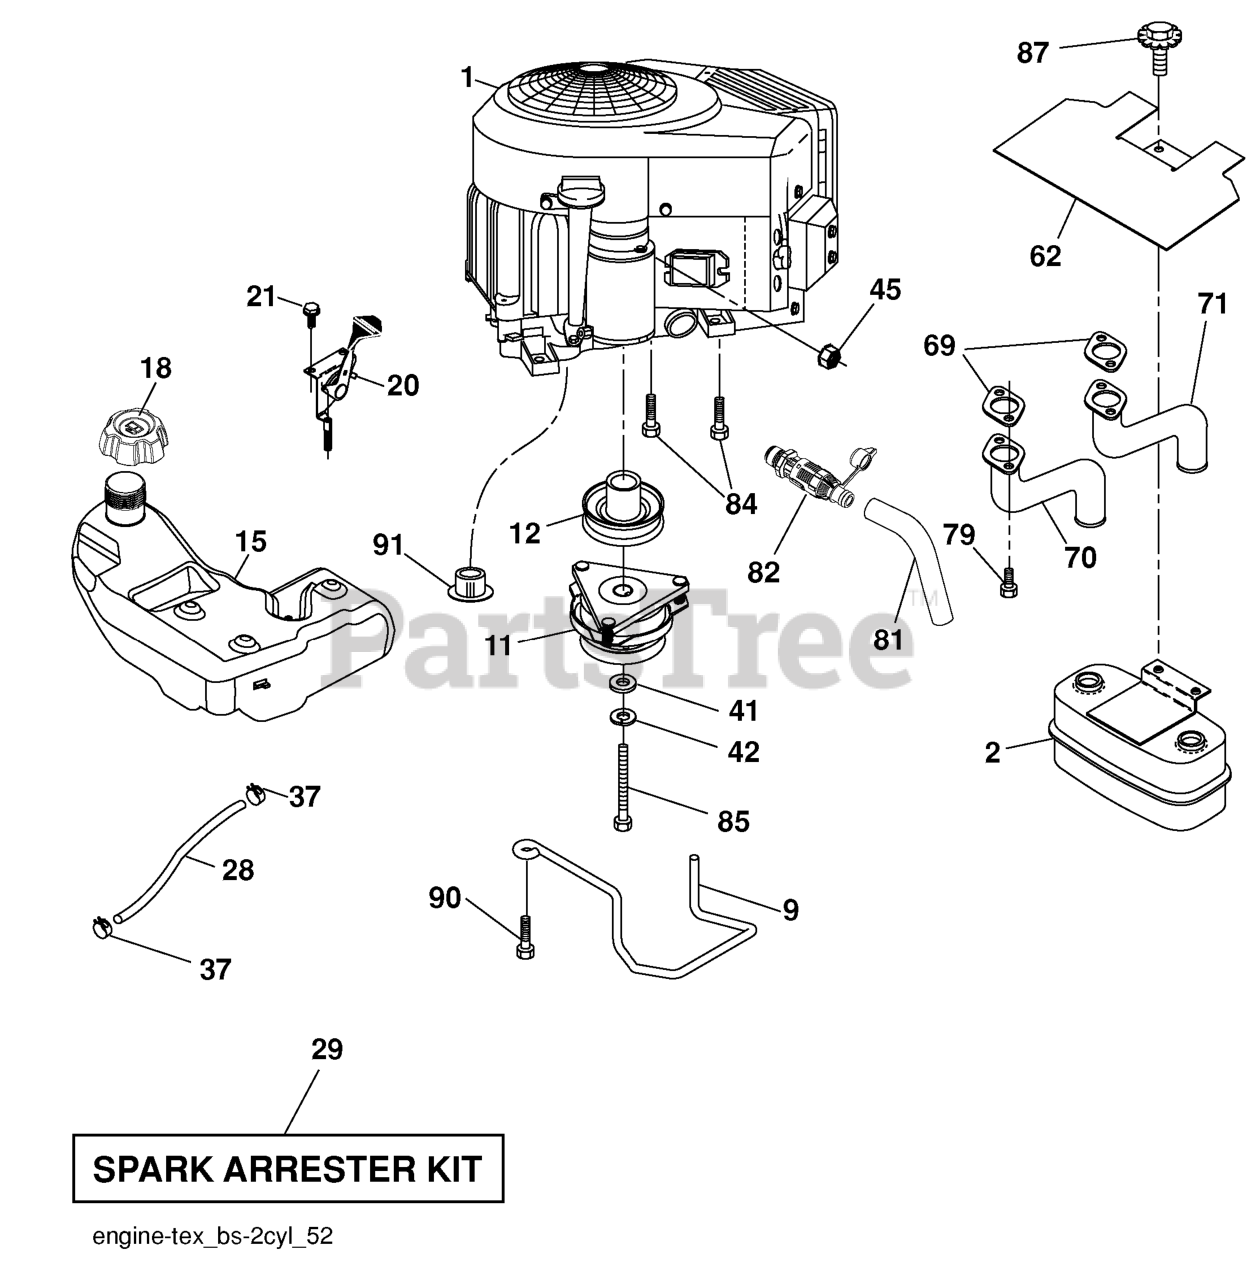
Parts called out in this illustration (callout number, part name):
2	MUFFLER.TWIN.CYL.LOW.TONE
9	KEEPER.BELT.ENGINE.4.2
11	CLUTCH.ELECTRIC.LT.48"*
12	PULLEY.ENGINE.TUFFTORQ
15	TANK.FUEL.SIDE-FILL.3.NON-EPA
18	RP CAP FUEL
20	CONTROL.TH/CK.COBRA.B&S.TWN.BK
21	SCREW.#10 X 0.750.BOS
28	LINE.FUEL.64"REAR.EMIS
29	KIT.SPARK ARRESTOR 794945 B&S
37	HOSE CLAMP
42	LOCKWASHER
45	NUT
62	SHIELD.HEAT.MUFFLER
69	GASKET.MUFFLER
70	RP.EXHAUST.TUBE.LH.BS/TWIN
71	EXHAUST.TUBE.RH.BS/TWIN
79	SCREW.SOCKET.HEAD.5/16-18
81	TUBE, DRAIN OIL ASM.
82	VALUE.OIL.DRAIN
84	SCREW.3/8-16
85	BOLT HEX 7/16-20X4-1/4"
87	BOLT.5/16-18UNCX3/4 W/SEMS.BLK
90	SCREW 3/8-16X1
91	BUSHING.1.375OD
